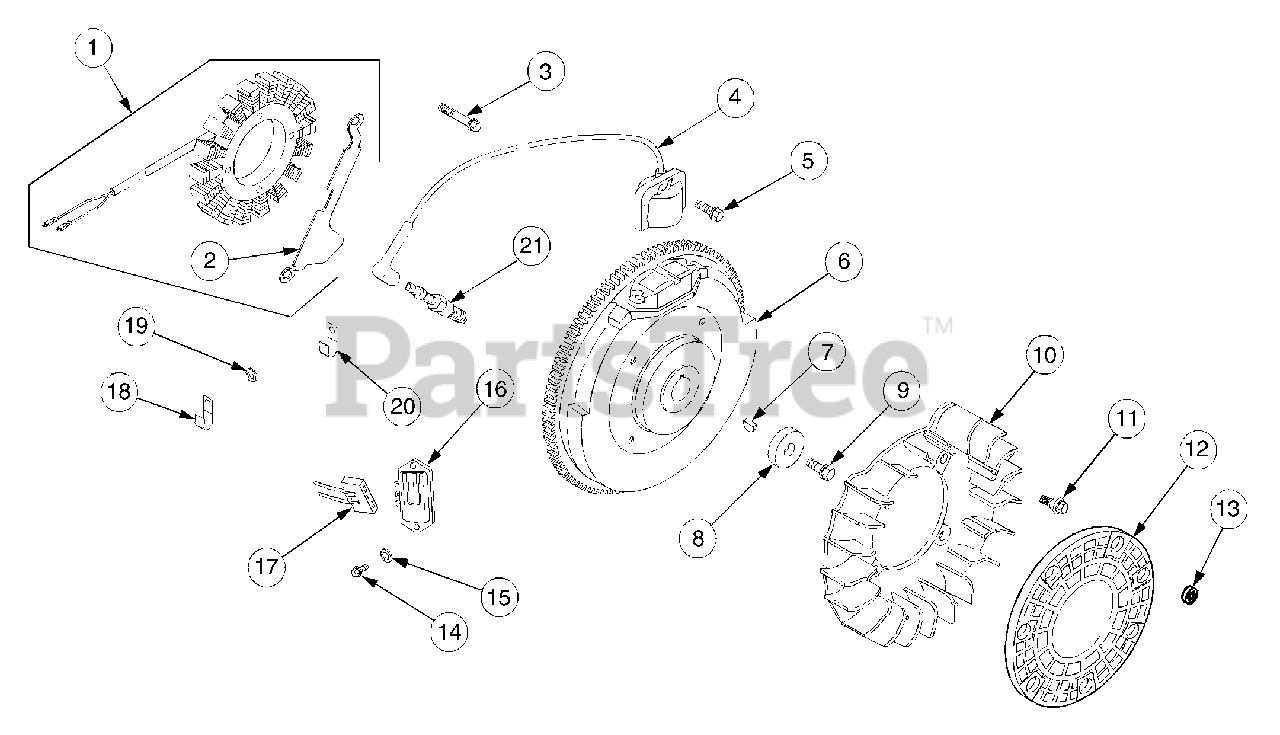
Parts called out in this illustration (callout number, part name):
1	Stator Kit, 15 Amp
2	Bracket, Stator Wire
3	Screw, Stator Mtg. M5 x .8 x 25
4	Module, Ignition
5	Screw, Module M5 x .8 x 20
6	Flywheel Assembly
8	Washer, Flywheel Mtg. Screw
9	Screw, Flywheel Mtg, M10 x 1.5 x 46
10	Fan
11	Bolt, Shoulder
12	Screen, Grass
13	Retainer
14	Screw Phillips Hd., #11-16 x .875
15	Washer, Plain
16	Regulator - Rectifier
17	Connector, Regulator-Rectifier
18	Clip, Cable
19	Washer, Plain 1/4"
21	Spark Plug
